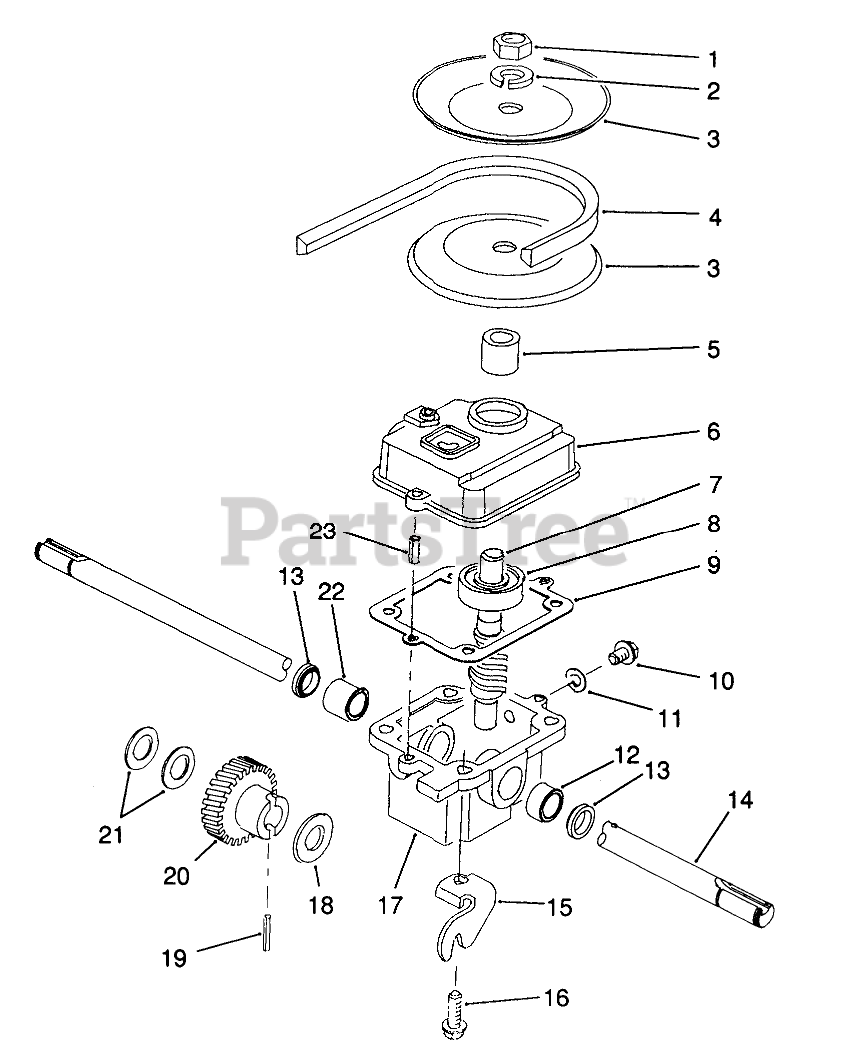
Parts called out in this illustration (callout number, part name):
1	NUT-JAM
2	WASHER-LOCK
3	PULLEY-DRIVEN HALF
4	V-BELT
5	SPACER - PULLEY
6	GEAR CASE COVER
7	SHAFT - WORM
8	BEARING
9	GASKET
10	NYLON SCREW
11	FILL PLUG GASKET
12	BUSHING
13	SEAL-OIL
14	OUTPUT SHAFT
15	TRACTION BRACKET
16	SCREW-HWHTF
17	GEAR CASE
18	THRUST WASHER
19	PIN-SPRING
20	GEAR - HELICAL
21	WASHER-PLAIN
22	BUSHING
23	3/16 X 1/2 ROLL PIN
